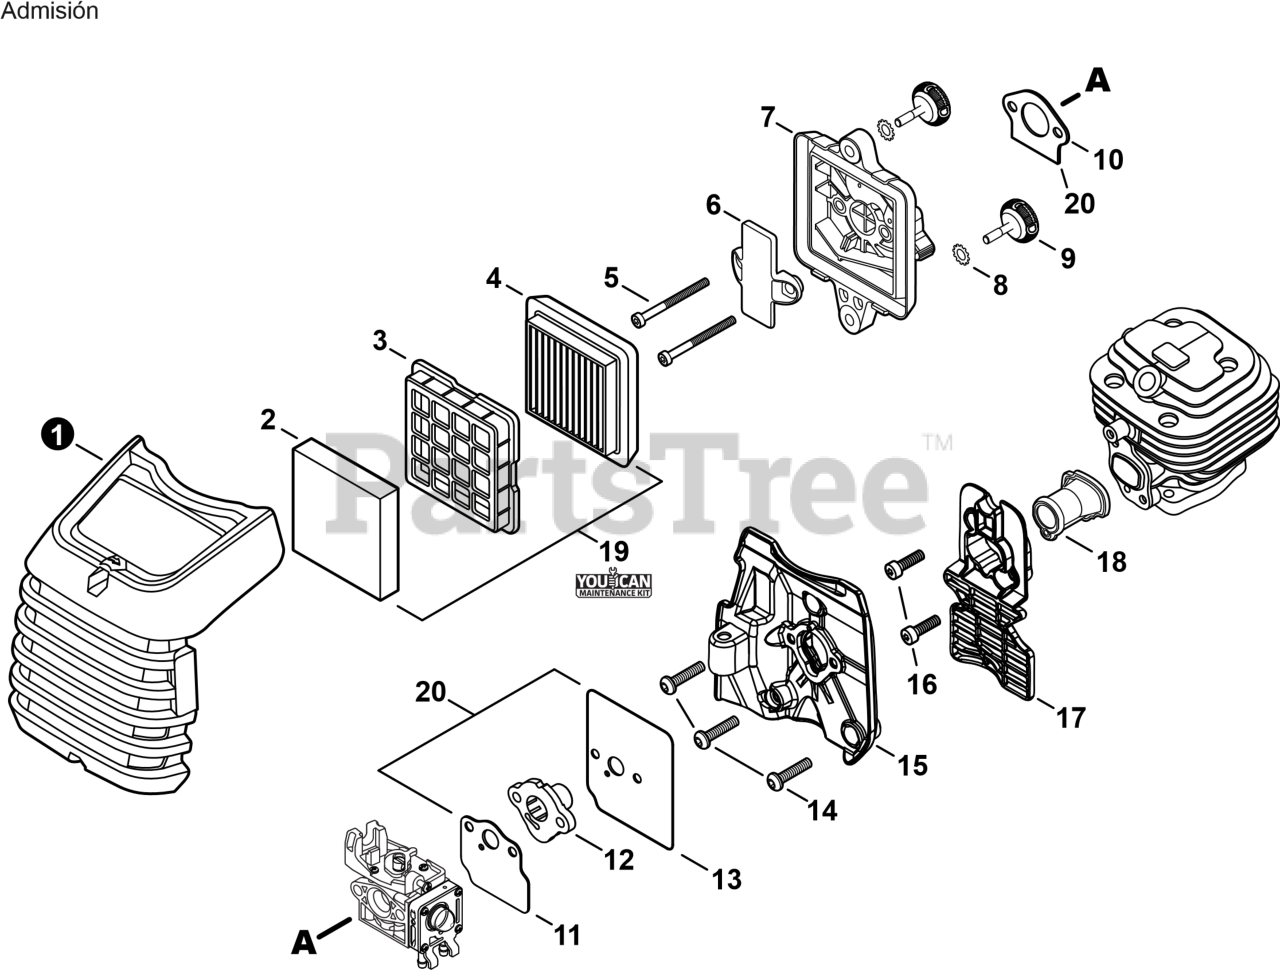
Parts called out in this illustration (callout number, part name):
1	COVER, AIR FILTER
2	PRE-FILTER, FOAM
3	RETAINER, PRE-FILTER
4	FILTER, AIR
5	BOLT, TORX 5×60
6	PLATE, PREVENT
7	CASE, AIR FILTER
8	WASHER, LOCK
9	THUMBSCREW
10	GASKET, INTAKE
11	GASKET, BOOT
12	BOOT, INTAKE
13	GASKET, INSULATOR PLATE
14	BOLT, TORX 5×16
15	PLATE, INSULATOR
16	BOLT, TORX 5×16
17	HOLDER, BELLOWS
18	BELLOWS, INTAKE
19	TUNE-UP KIT - YOUCANT
20	GASKET KIT
